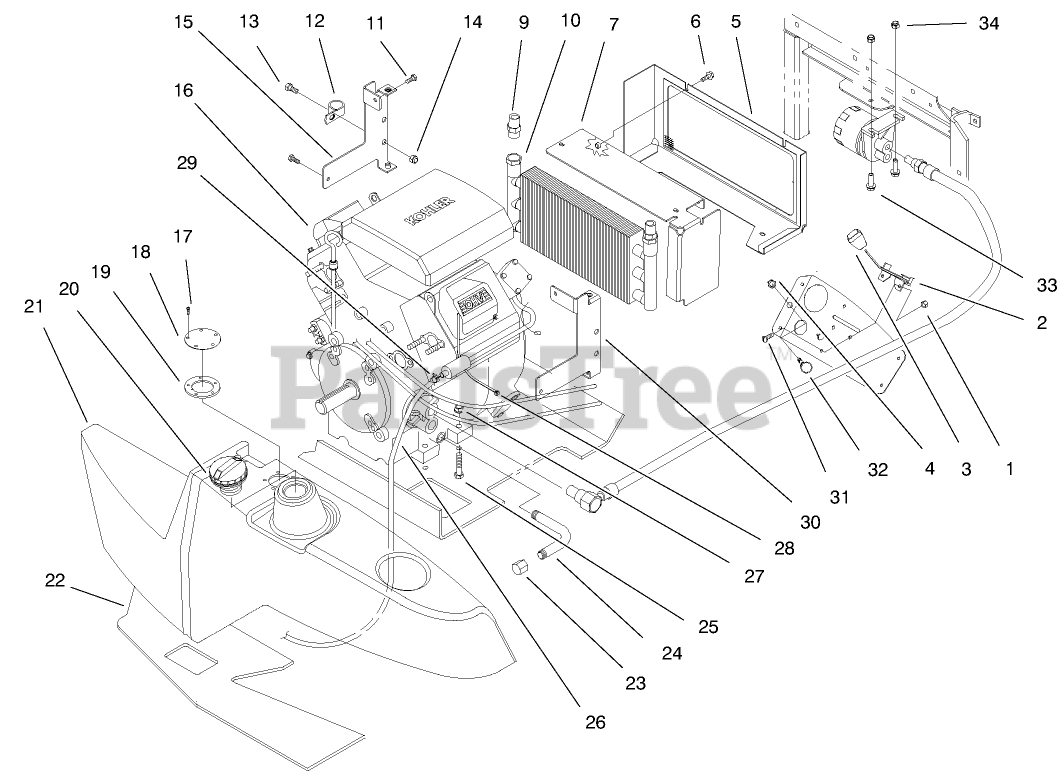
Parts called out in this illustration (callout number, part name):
1	NUT-LOCK, NI
2	THROTTLE CONTROL ASM
4	NUT-HJ
5	COOLER SHROUD ASM
6	SCREW-HHF
7	Cooler Shroud ASM
9	FITTING-ADAPTER
10	COOLER ASM
11	SCREW-HWH
12	CLAMP-R
13	SCREW-HH
14	NUT-LOCK, NI
15	Bracket-Rear
16	Engine-Kohler
17	SCREW-PPH
18	COVER-FUEL TANK OPENING
19	GASKET
20	CAP-FUEL
21	FUEL TANK ASM
22	FOAM-TANK, FUEL
23	CAP-PIPE
24	TUBE-DRAIN, OIL
25	SCREW-HH
26	HOSE-FUEL
27	NUT-LOCK, NI
28	TIE-CABLE
29	CLAMP-HOSE
30	Bracket-Front
31	SCREW-PPH
32	CONTROL-CHOKE
33	SCREW-HHF
34	NUT-LOCK, NI
